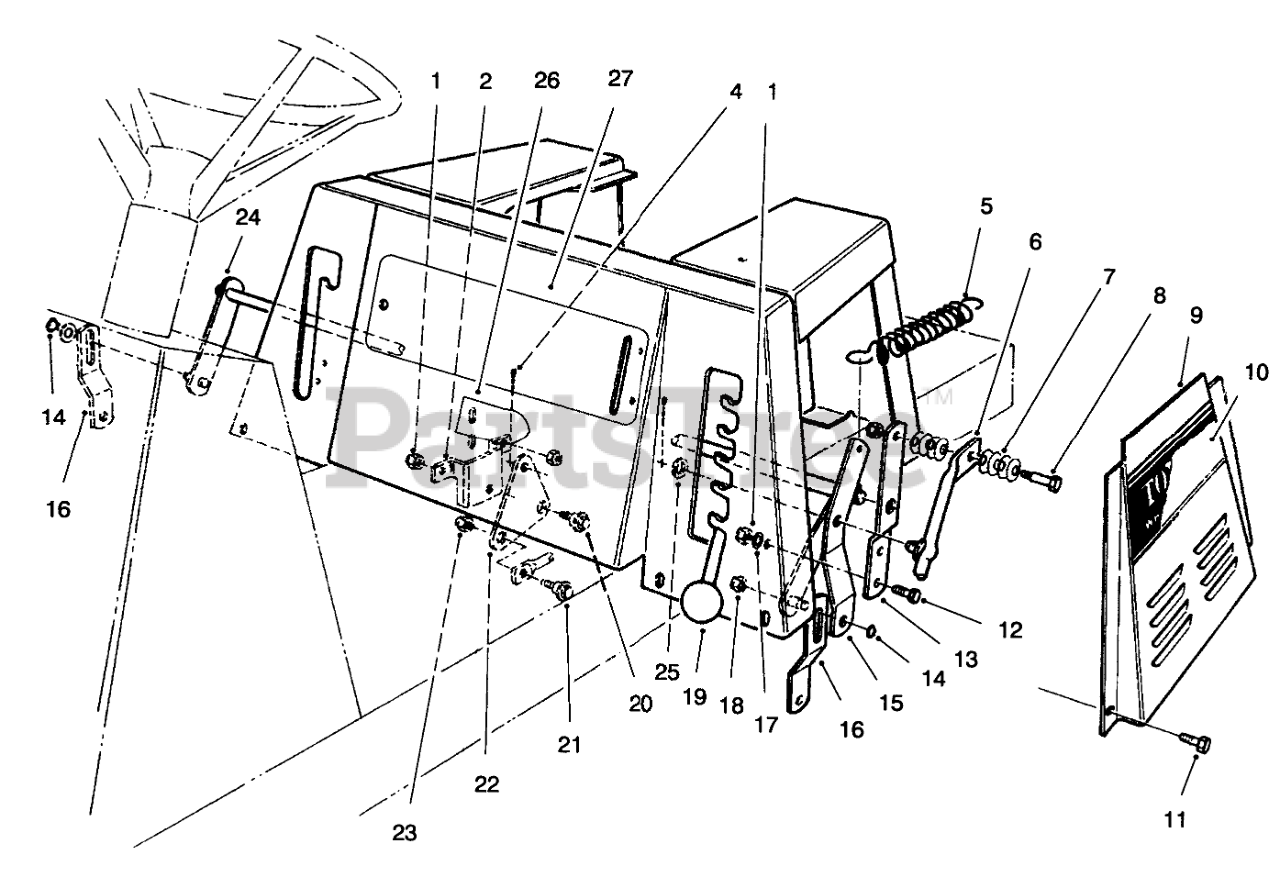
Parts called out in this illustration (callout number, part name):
1	NUT-LOCK, NI
2	BRKT-B.CRANK MTG
4	PIN-COTTER
5	SPRING-EXTENSION
6	HOC LEVER WA B
7	WASHER-BELLEVILLE
8	BOLT-SHOULDER
9	Panel L.H.-Base, Seat
10	DECAL - TORO 1132 LH
11	SCREW-HH
12	SCREW-HH
13	Bracket
14	RING-RETAINING
15	Bracket-H.O.C., Engage
16	Link-Deck Suspension
17	WASHER-PLAIN
18	NUT-LOCK, NI
20	SCREW-SHOULDER
21	SCREW-SHOULDER
22	BELLCRANK
23	NUT-HEX
24	Arm
25	WASHER-FLAT
26	DECAL - USA
27	DECAL - CONTROL PANEL
